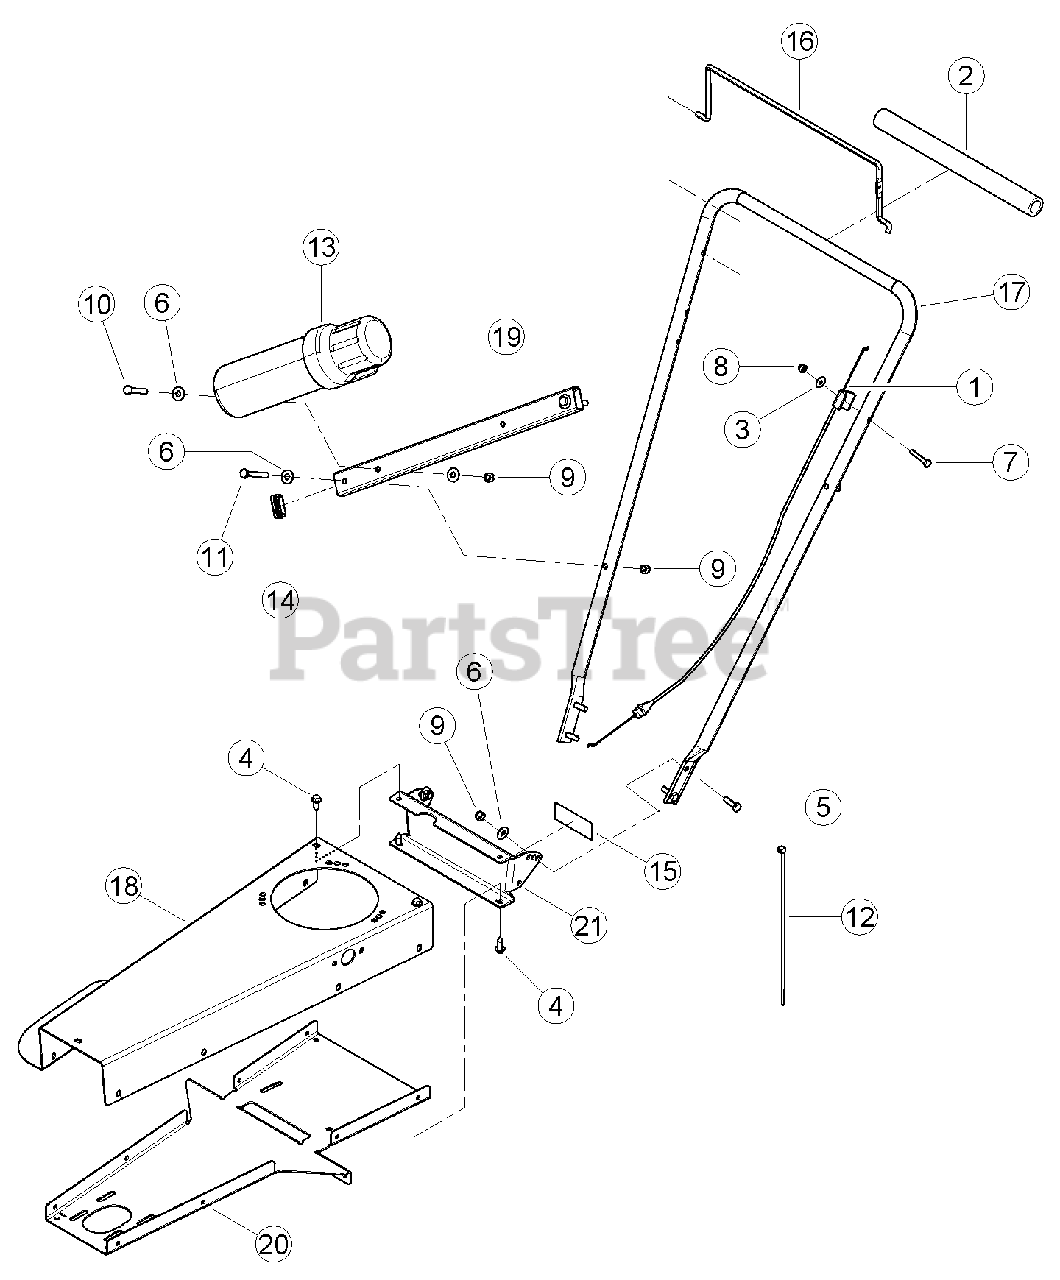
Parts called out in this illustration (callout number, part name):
1	CABLE, BRAKE CONTROL
2	PAD, FOAM HANDLEBAR
3	WASHER, 1/4 FLAT ZP
4	SCREW, 11/32 X 7/8 HWH AB THREAD ZP
5	BOLT, 5/16 X 1 HHCS GR5 NC ZP
6	WASHER, 5/16 FLAT ZP
7	BOLT, 1/4 X 1-1/2 HHCS GR5 ZP
8	NUT, 1/4 NE NYLOCK ZP
9	NUT, 5/16 NE NYLOCK ZP
10	BOLT, 5/16-18 X 1-3/4 HCS GR5 ZP
11	BOLT, 5/16 X 2-1/4 HCPS GR5
12	STRAP, 11 IN. BLACK TIE
13	CONTAINER, MANUAL (WAS 18008-00, REMOVED)
14	CAP, PLASTIC 3/4 X 1-1/2 TUBE
15	DECAL, ATLANTIC BRIDGE LTD INFO
16	BAIL, TRIMMER
17	HANDLEBAR, TRIMMER
18	BODY, TRIMMER
19	TUBE, CONTAINER MANUAL
20	BOTTOM, TRIMMER FRAME
21	CHANNEL, HANDLE SUPPORT
